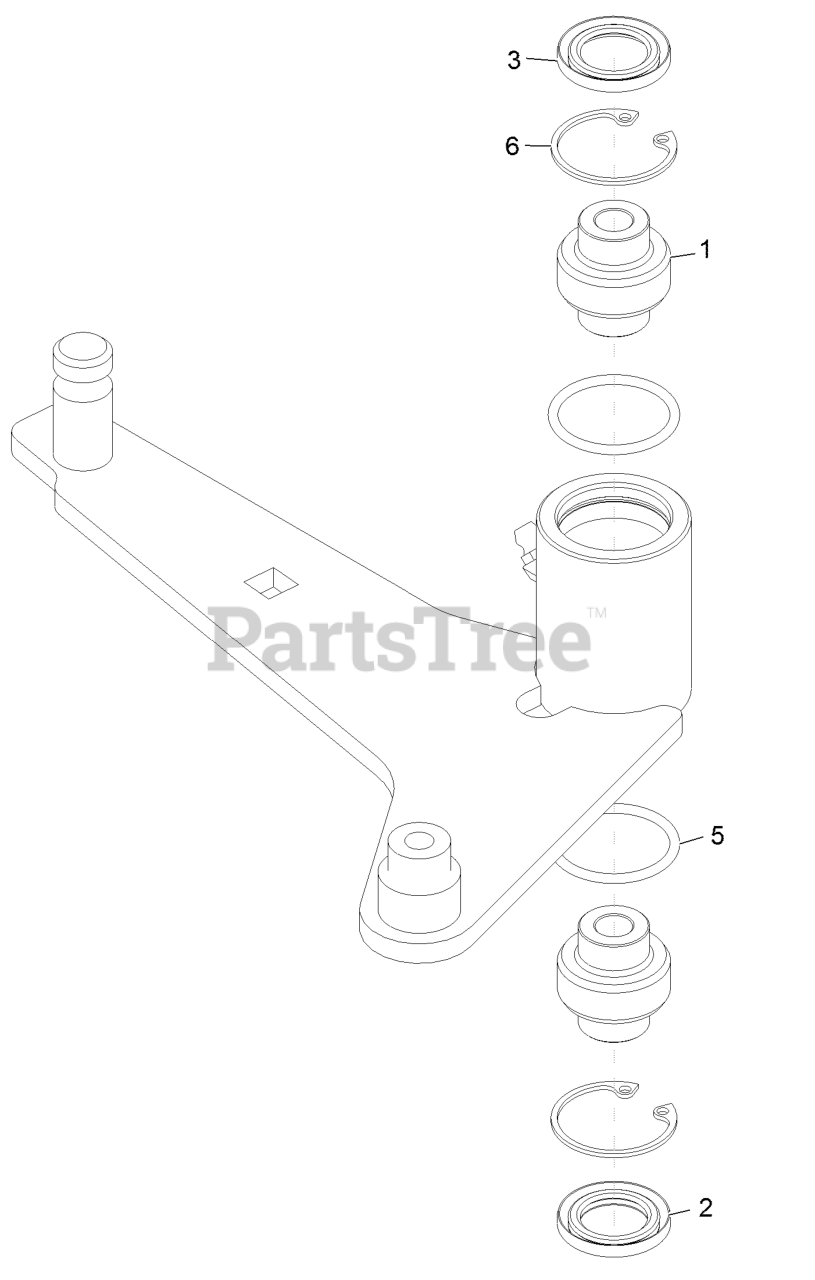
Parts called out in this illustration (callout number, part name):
1	Bearing-Spherical
2	Seal-Lip, Double
3	Seal-Single Lip
6	Ring-Retaining
